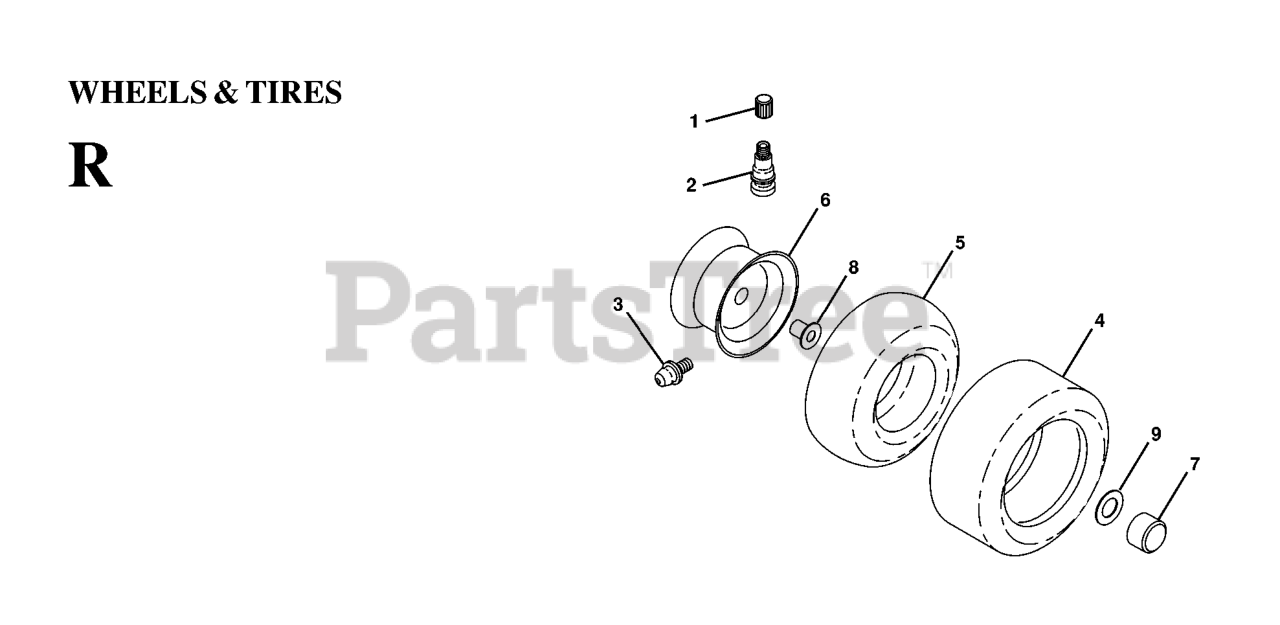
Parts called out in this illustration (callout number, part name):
2	VALVE STEM LT
3	FITTING LT
4	TIRE FRONT 15X6-6
5	TUBE.5.3/4.5/6
5	TUBE.16X6.5/7.5-8
6	RIM REAR 8"
6	RIM
7	CAP.HUB.FRONT.LT.BLACK
8	BEARING T
